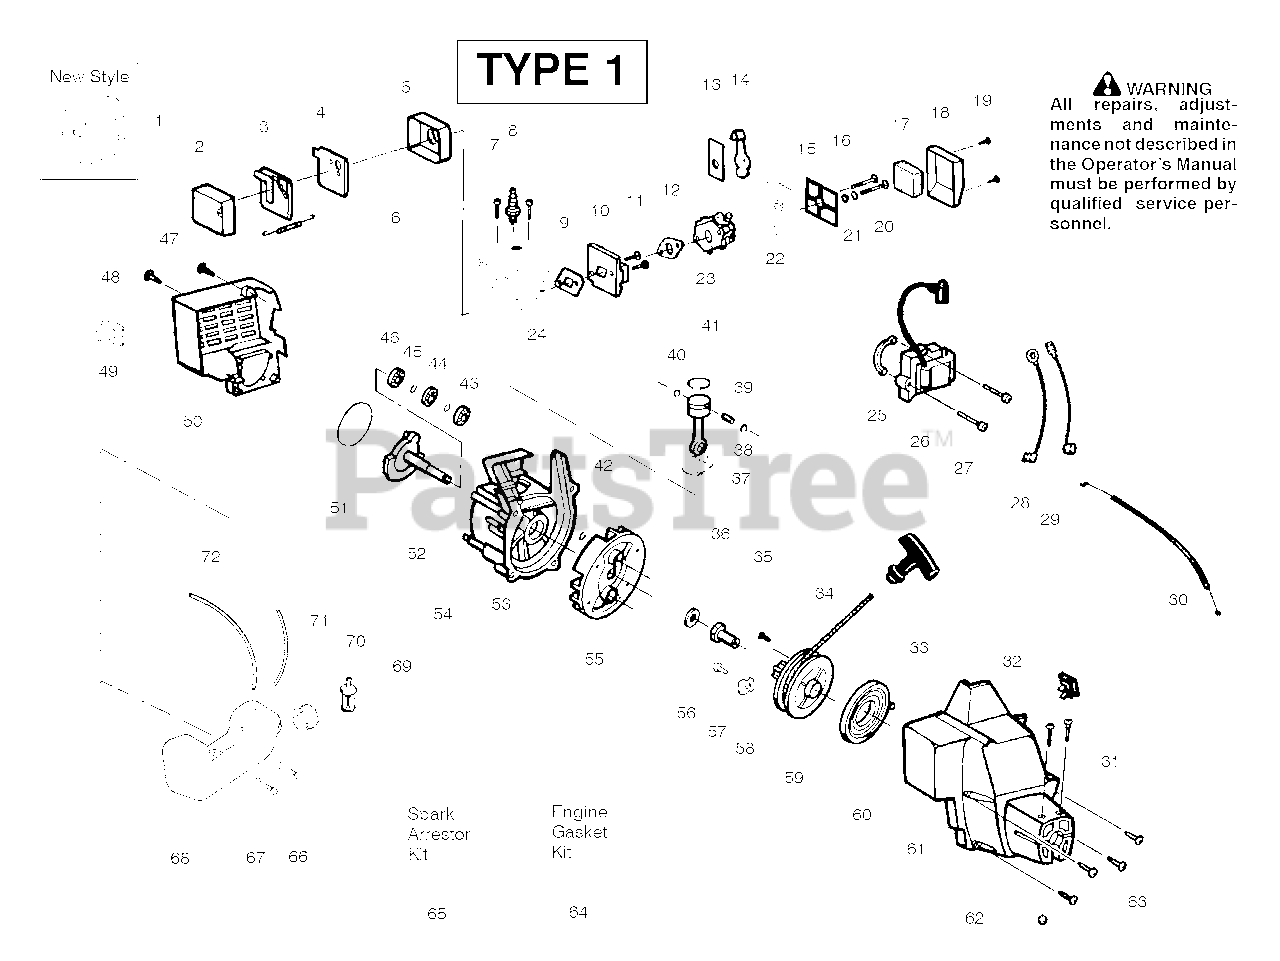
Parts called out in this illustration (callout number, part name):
1	Kit-Muffler Old Style
1	Kit-Muffler New Style
2	Muffler Cover
3	Muffler Baffle-Exit
4	Muffler Baffle-First
5	Muffler Body
6	Muffler Spring
7	Screw -Cylinder
8	Spark Plug (RCJ8Y)
9	Gasket Cyl./Carb.(kit)
10	Carb. Adapter
11	Screw-Carb Adaptor
12	Gasket-Carb.(kit)
13	Choke Plate
14	Choke Shutter
15	Filter Plate
17	Air Filter Foam
18	Air Filter Cover
19	Screw Air Box
21	Choke Spacer
23	Kit Carburetor Assy. Walbro (WA226)
23	Kit Carburetor Assy. Zama (C1U W7)
24	Kit Cylinder
25	Spacer Ignit. Module
26	Module Ignition
27	Screw Ignit. Module
28	Assy Ground Wire
29	Assy Lead Wire
30	Assy Throttle Cable
32	Kit Momentary Switch
33	Starter Handle
34	Kit Rope
35	Screw Rope Retain.
36	Coupling Drive
37	Gasket Cylinder (kit)
38	Assy Connecting Rod
39	Retainer Piston Pin
40	Ring Piston
41	Kit Piston
42	Retainer Ring C'shaft
43	Bearing Outer
44	Seal C'case
45	Retain. Ring C'case
46	Bearing Inner
47	Screw Shrd/Fan Hsg.
48	Screw
49	Guard Muffler
50	Shroud Rear
51	Gasket C'case
52	Assy Crankshaft
53	Assy Crankcase
54	Assy C'case & C'shaft
55	Assy Flywheel
56	Washer Flat
57	Screw Pulley
58	Retainer Pulley
59	Kit Starter Pulley
60	Starter Spring
61	Assy Fan Housing
63	Screw
64	Kit Engine Gasket
65	Kit Spark Arrestor Old Style
65	Kit Spark Arrestor New Style
68	Assy Fuel Tank
69	Assy Fuel Cap
70	Assy Fuel Pickup
71	Fuel Line Tank/Purge
72	Fuel Line Carb./Purge
